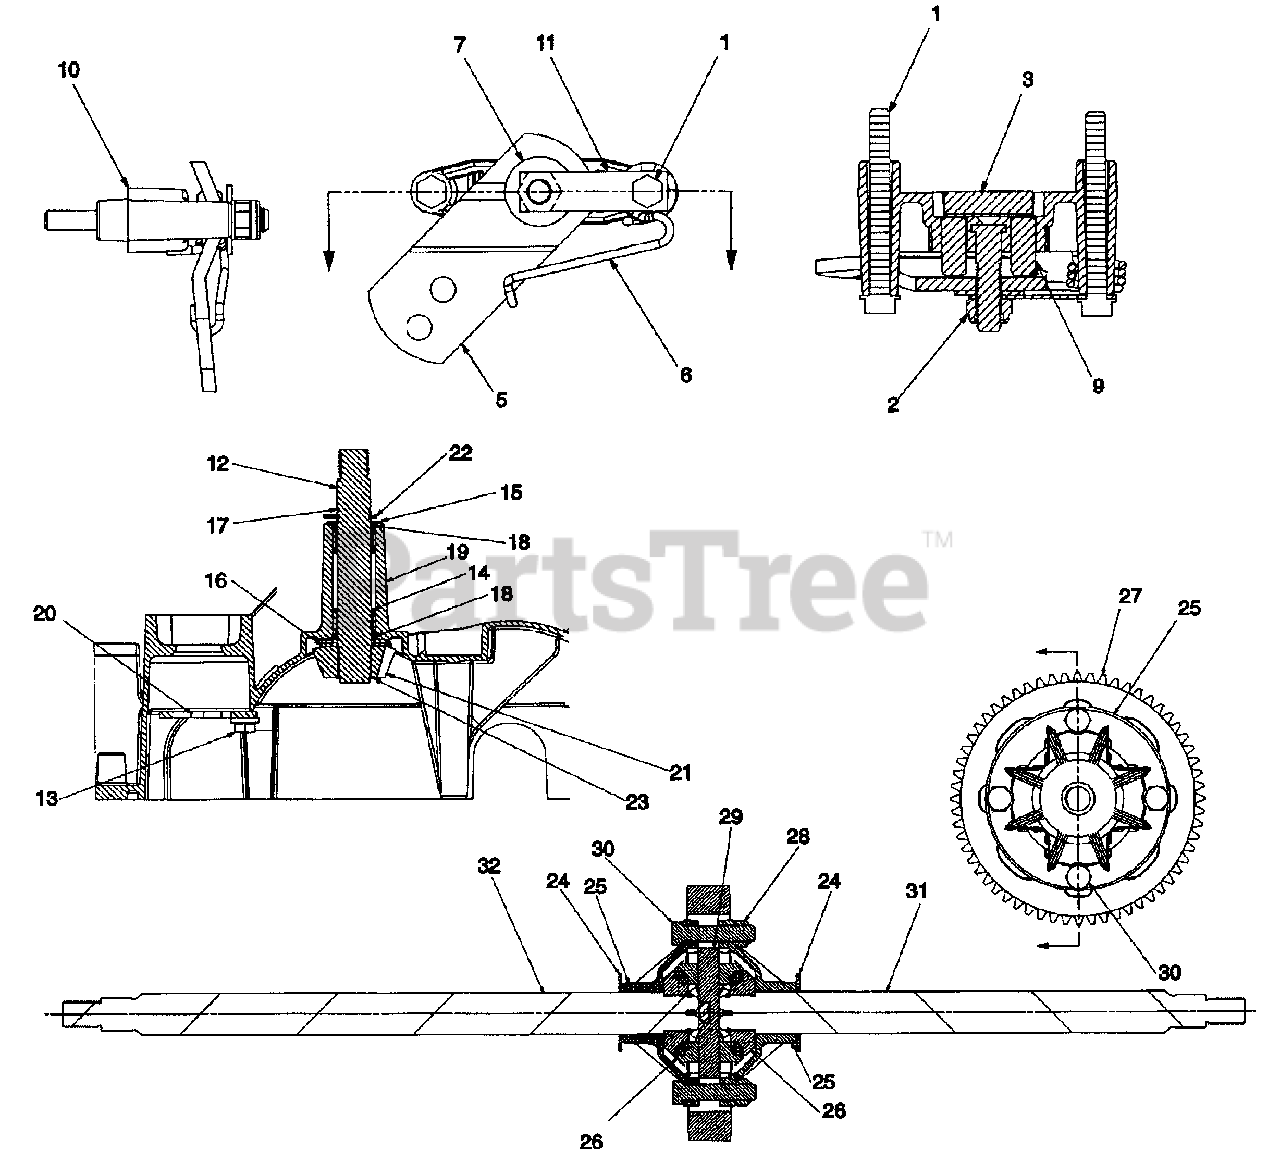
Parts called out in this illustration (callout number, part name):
1	Hex Wash. Hd. Scr. 1/4-20 x 2.37
2	Nylon L-Nut 5/16-24 Thd.
3	Brake Puck
5	Brake Arm
6	Torsion Spring
7	Fl-Wash. .343" I.D. x .88" O.D.
9	Brake Pin
10	Brake Yoke
11	Brake Anti Rotation Brkt.
12	Input Shaft
13	Hex Wash. Hd. AB-Tap Scr. 1/4-14 x .625" Lg
14	Needle Brg. .625" I.D.
15	Fl-Wash. 5/8" I.D. x 1" O.D.
16	Thrust Wash. .635" I.D. x 1.25" O.D
17	Wire Ring
19	Upper Housing
20	Lockout Plate
21	Bevel Gear
22	Retainer Ring
23	Retainer Ring
24	Fl-Wash. 1" I.D. x 1.8" O.D.
25	Differential Housing
26	10T Miter Gear
27	Spur Gear 60T
28	Hex L-Nut 3/8-24 Thd.
29	Cross Shaft
30	Hex Bolt 3/8-24 x 1.75" Lg.(Gr. 5)
31	Axle Ass'y.--L.H.
32	Axle Ass'y.--R.H.
